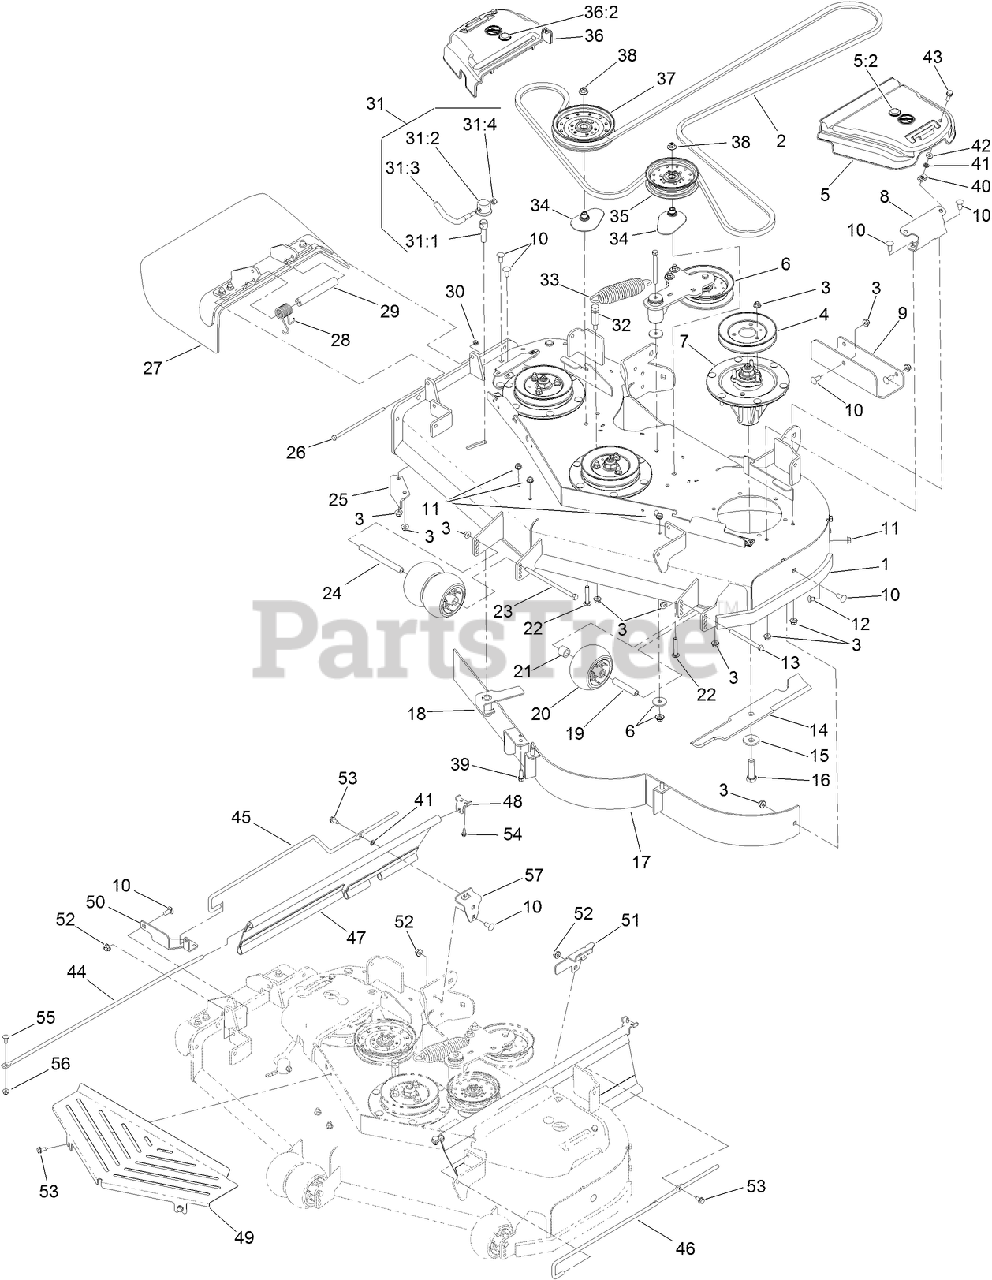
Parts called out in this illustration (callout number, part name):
1	DECK DECAL ASM
2	BELT-V
3	NUT-HF, NI
4	PULLEY
5	LH BELT COVER ASM
5:2	PLUG-PLASTIC
6	IDLER ARM ASM
7	SPINDLE ASM
8	BRACKET-COVER, BELT
9	PLATE-SKID
10	SCREW-CARR
11	NUT-HHF, WHIZ
12	SCREW-CARR
13	SCREW-HH
14	BLADE-16.5 INCH (HIGH FLOW)
15	Washer-Blade Bolt, Heavy
16	SCREW-BLADE
18	ADJUSTABLE BAFFLE ASM
19	TUBE-SPANNER
20	ROLLER-SCALP, ANTI
21	TUBE-SPACER
22	BOLT-CARR, SHORT NECK
23	SCREW-HH
24	SPACER-WHEEL
25	BAFFLE-DISCHARGE
26	SCREW-HH
27	RUBBER DEFLECTOR ASM
28	SPRING-TORSION
29	SPACER
30	NUT-LOCK, NI
31	LEVER ASM
31:1	Screw-Lock
31:2	CAP-LOCK
31:3	Lever-Lock
31:4	NUT-LOCK, NI
32	ANCHOR-SPRING, TALL
33	SPRING-EXTENSION
34	SPACER-PULLEY
35	PULLEY-IDLER, FLAT
36	RH BELT COVER ASM
36:2	PLUG-PLASTIC
37	PULLEY-IDLER, FLAT
38	NUT-FLANGE, NI
39	SCREW-HWH
40	NUT-U
41	NUT-PUSH
42	WASHER-THRUST
43	SCREW-HHF
44	ROD-SUPPORT, UPPER
45	ROD-SUPPORT, LOWER (RH)
46	ROD-SUPPORT, LOWER (LH)
47	GUARD-SIDE
48	BRACKET-MOUNTING, UPPER
49	SHIELD-FRONT
50	BRACKET-MOUNTING, FRONT
51	BRACKET-MOUNTING, REAR (LH)
52	NUT-HF, NI
53	SCREW-HWHTF
54	SCREW-HWH
55	SCREW-CARR
56	NUT-HF, NI
57	BRACKET-MOUNTING, REAR (RH)
